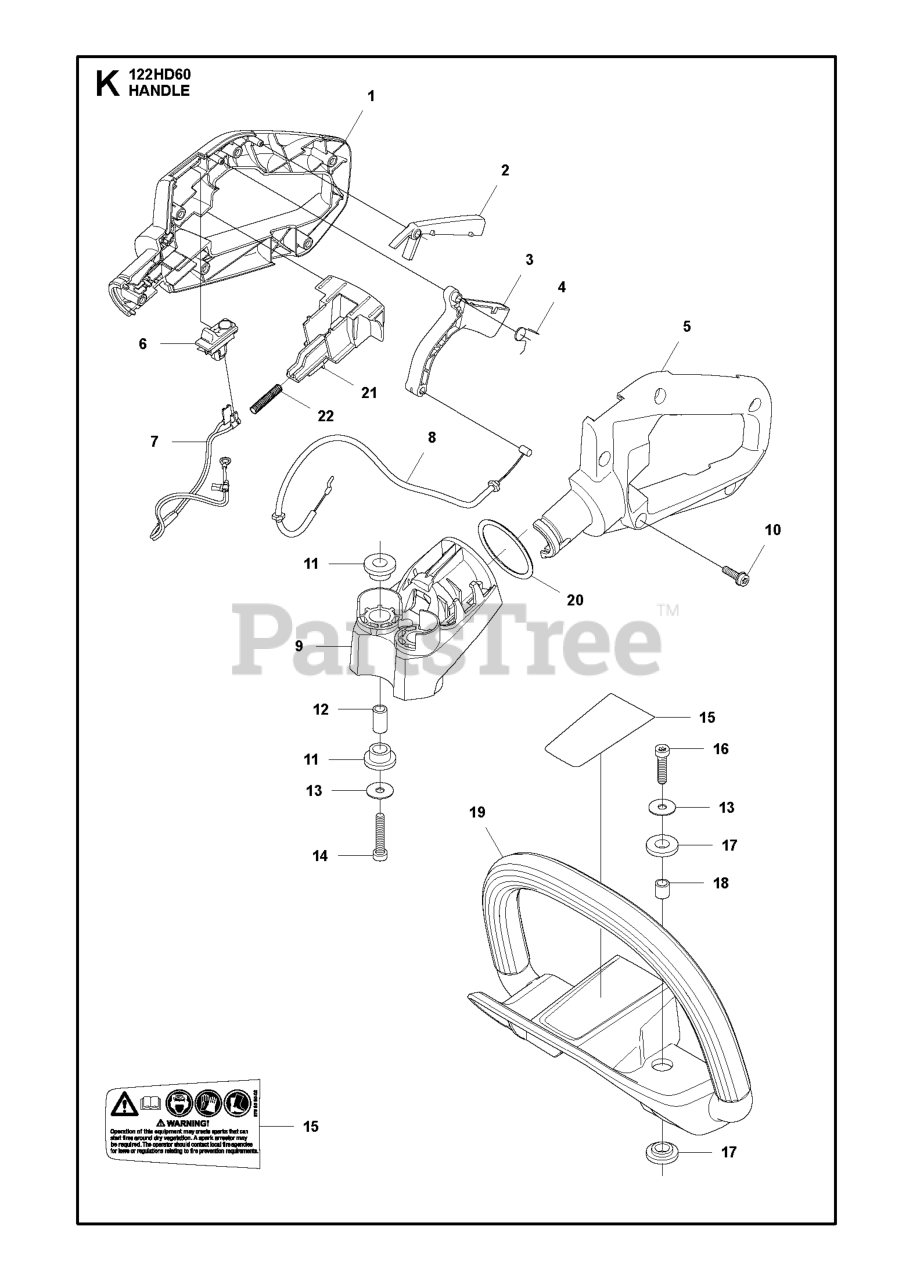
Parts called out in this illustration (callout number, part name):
1	REAR HANDLE
2	THROTTLE LOCKOUT
3	THROTTLE CONTROL
5	REAR HANDLE
6	STOP BUTTON
7	SHORT CIRCUIT CABLE
8	THROTTLE CABLE ASSY
9	HANDLE HOLDER
11	ANTIVIBRATION ELEMENT
17	ANTIVIBRATION ELEMENT
21	LOCKING BUTTON
22	RECOIL SPRING
